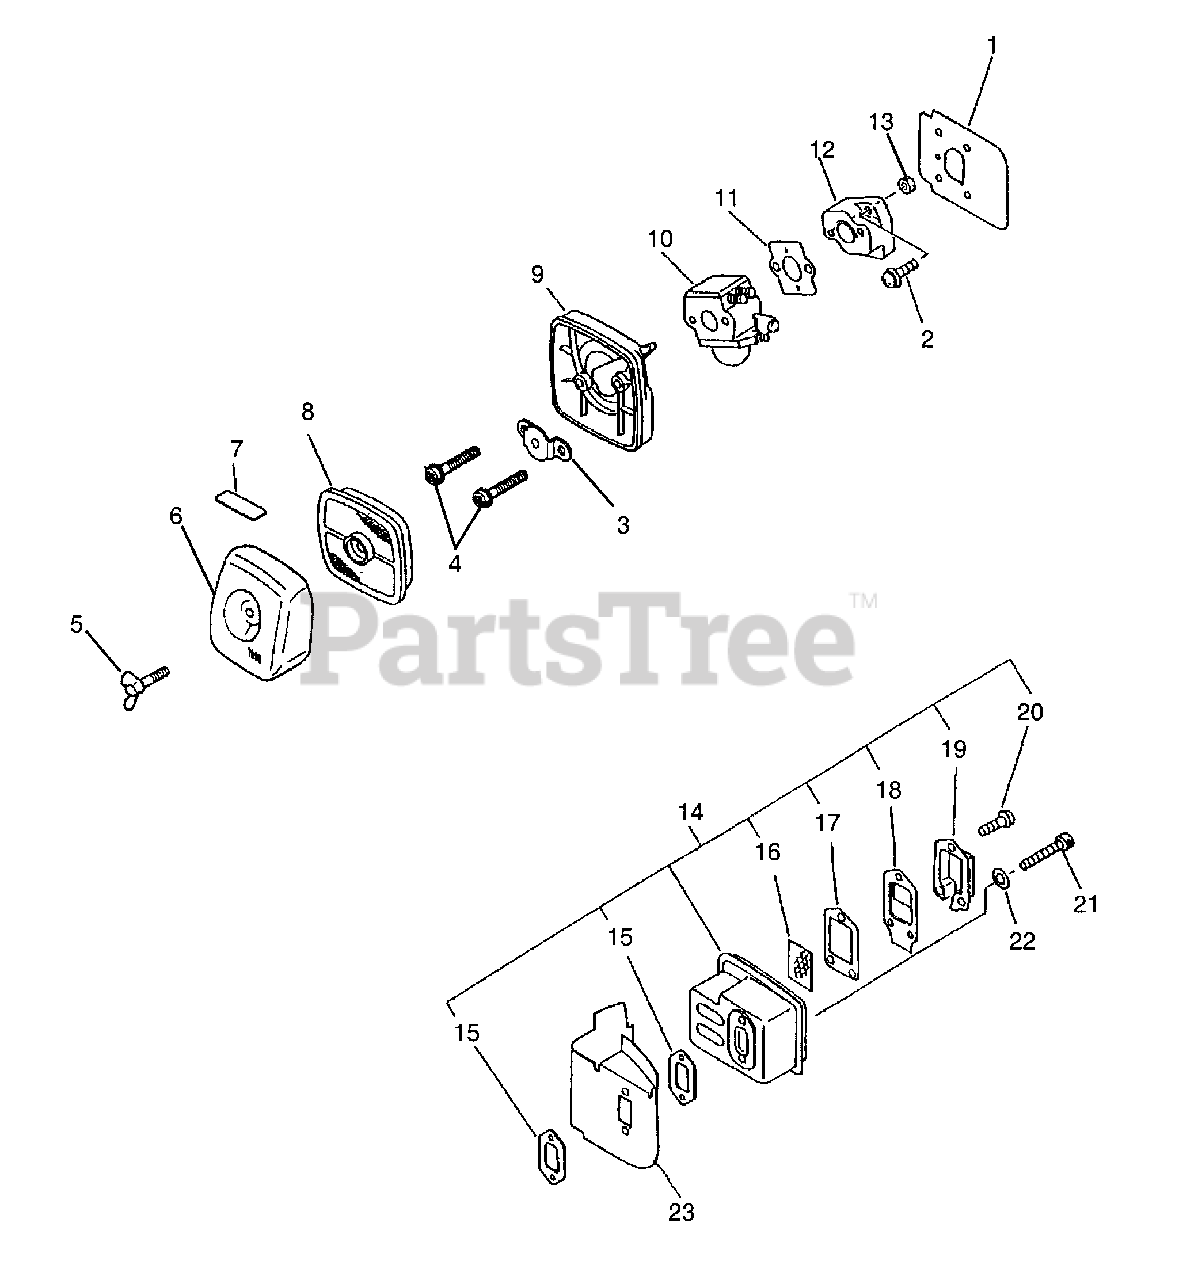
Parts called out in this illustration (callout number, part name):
1	SHIELD, INTAKE
2	SCREW - 5X20
3	PLATE, PREVENT
4	SCREW - 5X65
5	THUMBSCREW
6	COVER, AIR FILTER - GRAY
7	LABEL - CHOKE
8	FILTER, AIR
8	FILTER, AIR - SINGLE LAYER
9	AIR FILTER CASE ASSY
10	CARBURETOR C1U-K51
11	GASKET, INTAKE
12	INSULATOR, INTAKE
14	MUFFLER ASSY
15	GASKET, EXHAUST
16	SCREEN, SPARK ARRESTOR
17	GASKET, EXHAUST
18	GASKET, EXHAUST - INNER
19	GUIDE, EXHAUST - OUTER
20	SCREW - 4X10
21	SCREW - 5X50
22	WASHER - 5
23	SHIELD, EXHAUST
